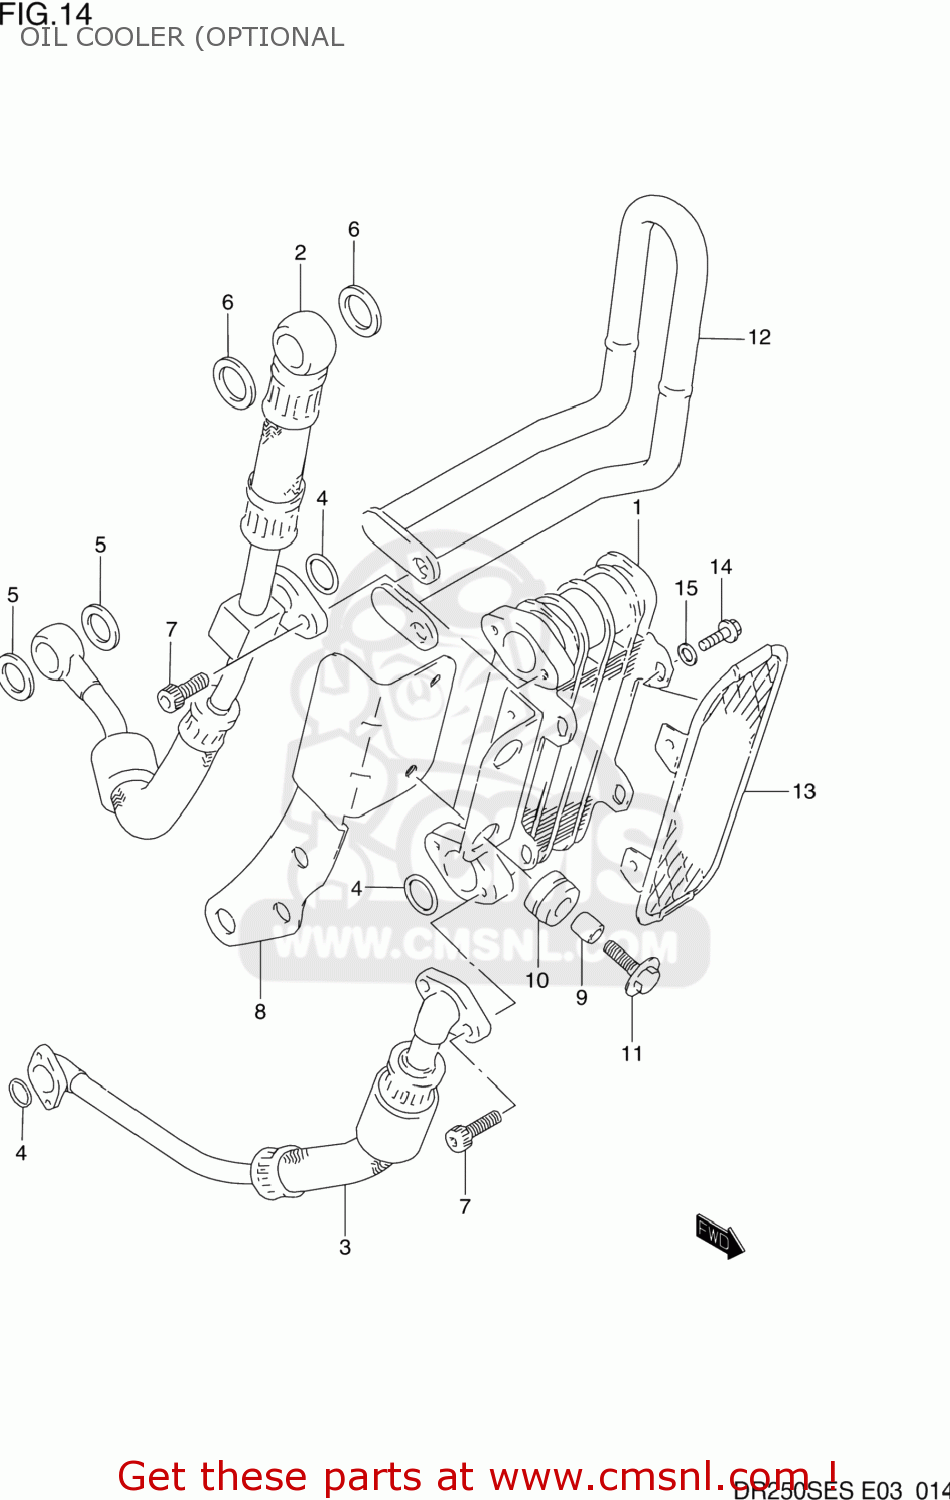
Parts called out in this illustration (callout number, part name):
1	COOLER ASSY,OIL
2	HOSE,OIL COOLER UPR
3	HOSE,OIL COOLER LWR
4	O RING(D:2.4,ID:12.3)
5	GASKET(12X17X1) (NAS)
6	GASKET(16X22X2) (NAS)
7	BOLT
8	BRACKET,OIL COOLER
9	SPACER (6.8X10X10)
10	CUSHION
11	BOLT 6X20
12	GUARD,OIL COOLER
13	BUMPER,OIL COOLER
14	BOLT
15	WASHER,LOCK
